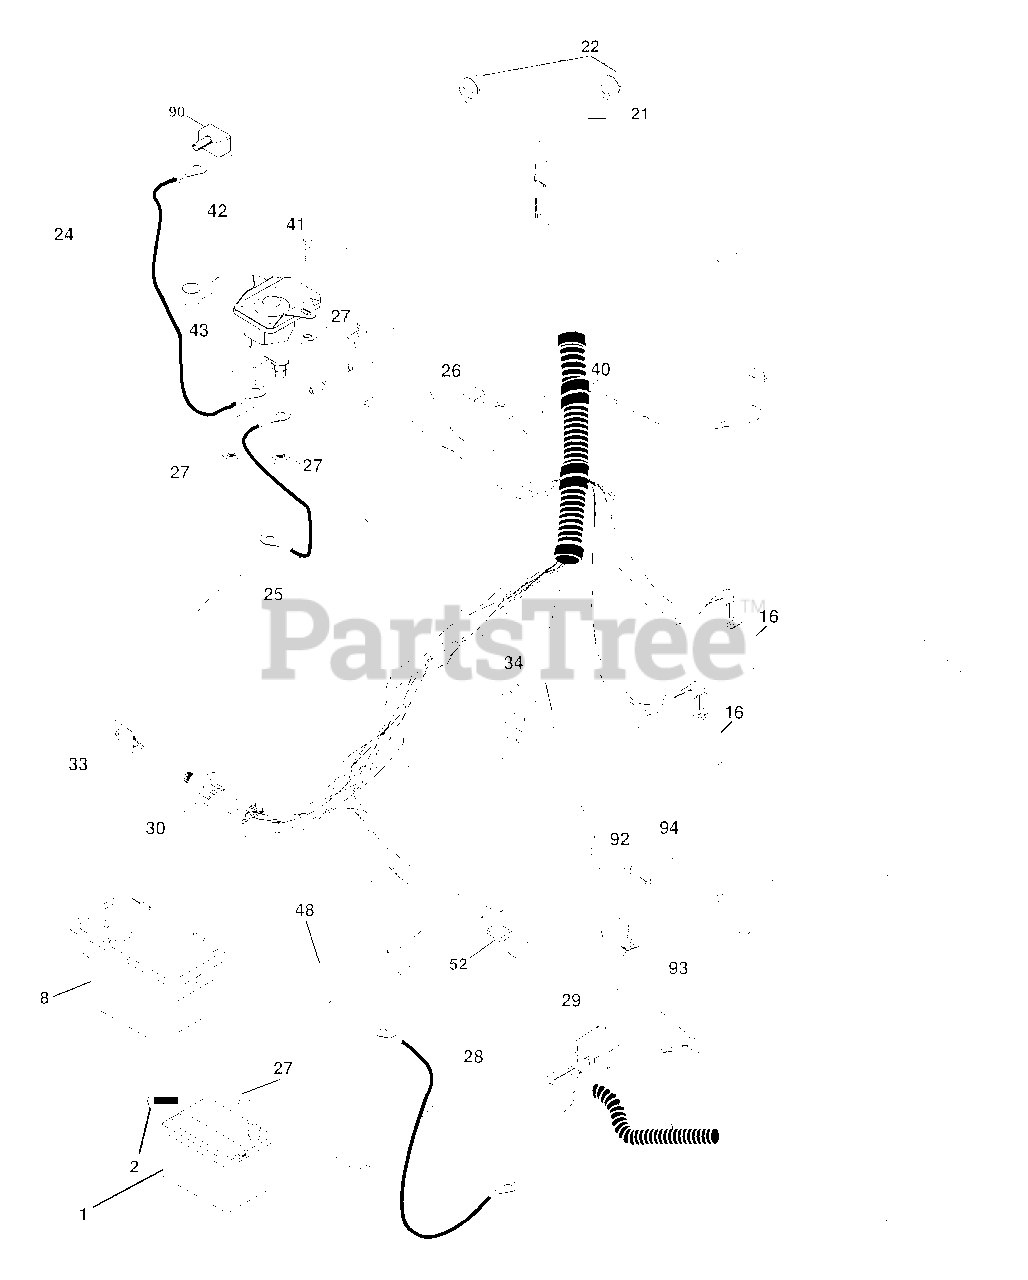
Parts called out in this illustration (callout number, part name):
1	Battery
2	Bolt Hex Hd 1/4-20 unc x 3/4
8	Box Battery
16	Switch Interlock
21	Harness Asm Light W/4152j
22	Bulb Light #1156
24	Cable Battery 6 Ga. 11"red
25	Cable Battery
26	Fuse 20 AMP
27	Nut Keps Hex 1/4-20 unc
28	Cable Ground 6 Ga. 12" Black
29	Switch Seat
30	Switch Ign
33	Key Ign
34	Switch Light/Reset
40	Harness Ign
41	Bolt Blk Fin Hex 1/4-20
42	Cover Terminal Red
43	Solenoid
48	Adapter Ammeter
52	Protection Wire Loop
90	Cover Terminal Battery
92	Harness Pigtail
93	Screw Plastite 10-14 x 2.0
94	Module Reverse ROS
